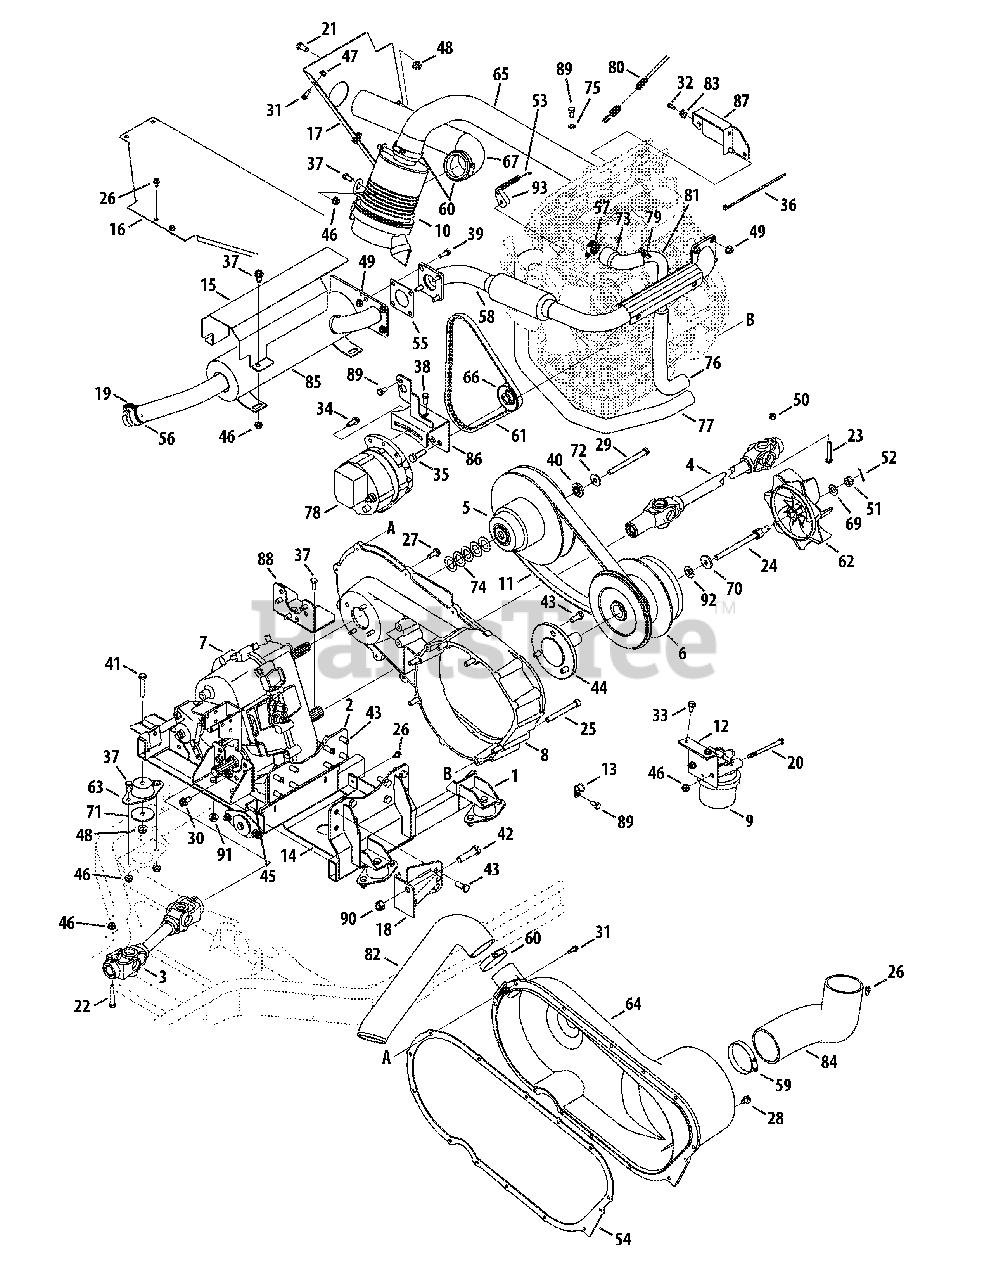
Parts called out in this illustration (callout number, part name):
1	Tray Assembly, Engine, Yanmar
2	Tray Assembly, Engine, Trans
3	Shaft Assembly, Rr/prop
4	Shaft Assembly, Frt/prop, Hilliard
5	Clutch Assembly, Cvt, Driven
6	Clutch Assembly, Driver, Yanmar
7	Case Assembly, Transfer
8	Housing Assembly, Cvt, Machine
9	Filter Assembly, Diesel
10	Filter Assembly, Air Cleaner
10	Filter, Air
10	Valve, Dust
11	Belt, Cvt, 4x4
12	Bracket, Fuel Filter, Yanmar
14	Shield, Oil, Engine
15	Exhaust, Shield, Heat
16	Plate, Heat, Shield, Yanmar
17	Plate, Baffle
18	Bracket Mount, Lower, Alternator
20	Hex Head Screw, 5/16-18, 4.00
21	Hex Head Screw, 3/8-16, .75
22	Hex Head Screw, 5/16-18, 2.00
23	Hex Head Screw, 5/16-18, 1.875
24	Hex Head Screw, 7/16-20, 5.00
25	Screw, M10-1.50
26	Screw, Tt, 1/4-20, 0.500, Hxindwsh
27	Screw, Tt, 5/16-18, 1.000, Hxindwsh
28	Screw, B, 5/16-12, 0.500, Hxindwsh
29	Hex Head Screw, 3/8-24, 4.50
30	Screw, Tt, 3/8-16, 0.750, Hxindwsh
31	Screw, Tt, 1/4-20, 0.750, Hxindwsh
32	Screw, #10-16, 0.625, Hxindwsh
33	Screw, 5/16-12, 0.750, Hxindwsh
34	Hex Head Screw, 5/16-18, .875
35	Hex Head Screw, M8-1.5, 35 mm
36	Tie, Cable
37	Hex Head Screw, 5/16-18, .75
38	Hex Head Screw, 1/4-20, .75
39	Hex Head Screw, 5/16-18, .875
40	Spacer, Shoulder
41	Hex Head Screw, 3/8-16, 2.00
42	Hex Head Screw, 1/2-13, 2.00
43	Hex Head Screw, M10-1.5, 25mm
44	Shaft, Output, Yanmar, Tapered
46	Nut, Flange Lock, 5/16-18, Nylon
47	Nut, Flange Lock, 1/4-20, Nylon
48	Nut, Flange Lock, 3/8-16, Nylon
49	Nut, Flange Lock, 5/16-18, Sd Lk
50	Nut, Hex Lock, 5/16-18, Ctrlk
51	Nut, Hex, 1/2-20, Gr5, Slot
52	Pin, Cot, 3/32, 1.0
53	Spring, Extension
54	Gasket, CVT Cover
55	Gasket, Engine
56	Spark Arrester Screen
57	Clamp, Hose, Adj
58	Pipe, Exhaust, Yanmar
59	Clamp, Hose, Adj
60	Clamp, Hose, Adj 2-3"
62	Impeller, Blo
63	Compression Mount, Eng, Head
64	Cover, Cvt
65	Hose, Air Inlet, Yanmar
67	Hose, Air Inlet
68	Washer, Flat, .330 x .630 x .0635
69	Washer, Flat, .510 x 1.00 x .060
70	Washer, Flat, .450 x 1.250 x .164
71	Washer, Flat, .38 x 2.00 x .12
72	Washer, Bell, .396 x 1.140 x .095
73	Tube, Upr, rr, Rdtr, Yanmar
74	Washer, Flat, .793 x 1.368 x .025
75	Washer, Lock, 5/16 Ext Tooth
76	Tube, lwr, rdtr
77	Hose, Rdtr, Rr, Yanmar
78	Alternator, Aux, 65 Amp
79	Fitting, Petcock, 1/8"
80	Cable, Throttle Control, Yanmar
81	Tube, Rdtr
82	Hose, CVT, Exhaust
83	Clamp, Casing
84	Tube, Cvt, Intake
86	Assembly Mount, Alternator
87	Bracket, Throttle Mount
88	Bracket, Transmission Mount, rr
89	Hex Head Screw, M8-1.25
90	Nut, Hex Lock, 1/2-13
91	Nut, M8-1.25
92	Spacer, Shoulder
93	Bracket, Throttle, Spring, Return
